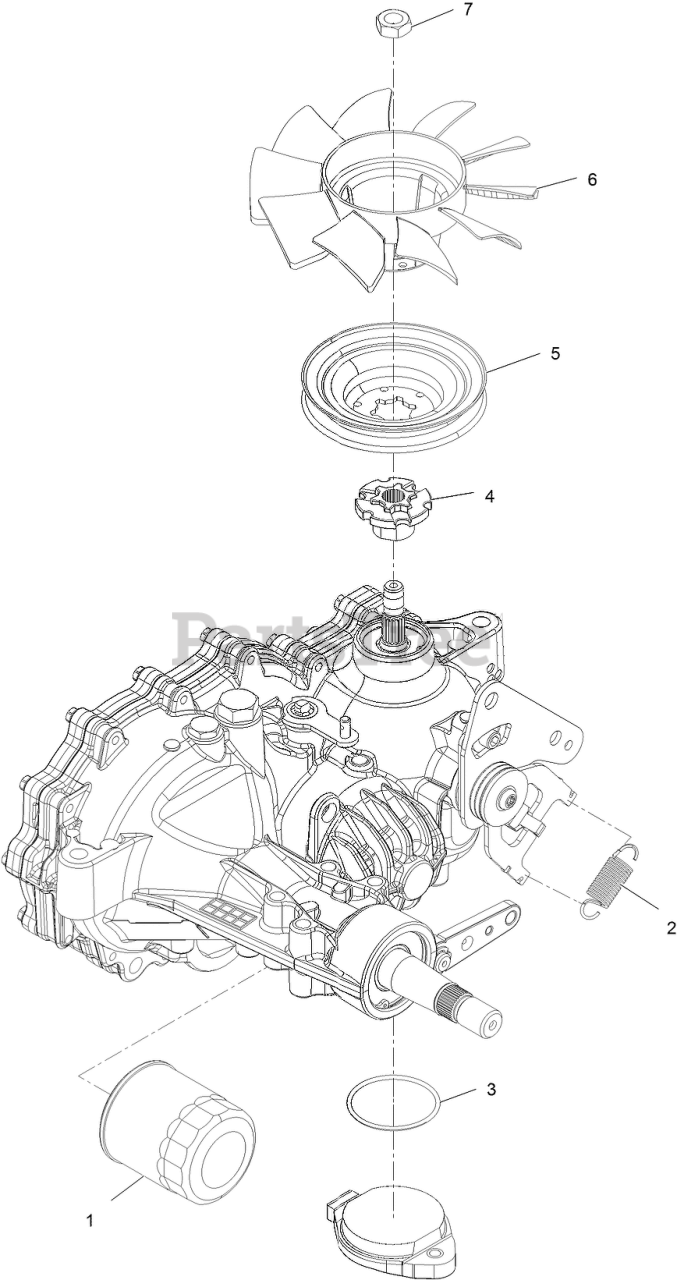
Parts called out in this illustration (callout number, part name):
1	ELEMENT-OIL FILTER, HYD
2	SPRING-EXTENSION
3	O RING-SEAL
4	HUB-PULLEY
6	FAN-7.0 INCH (10 BLADE)
